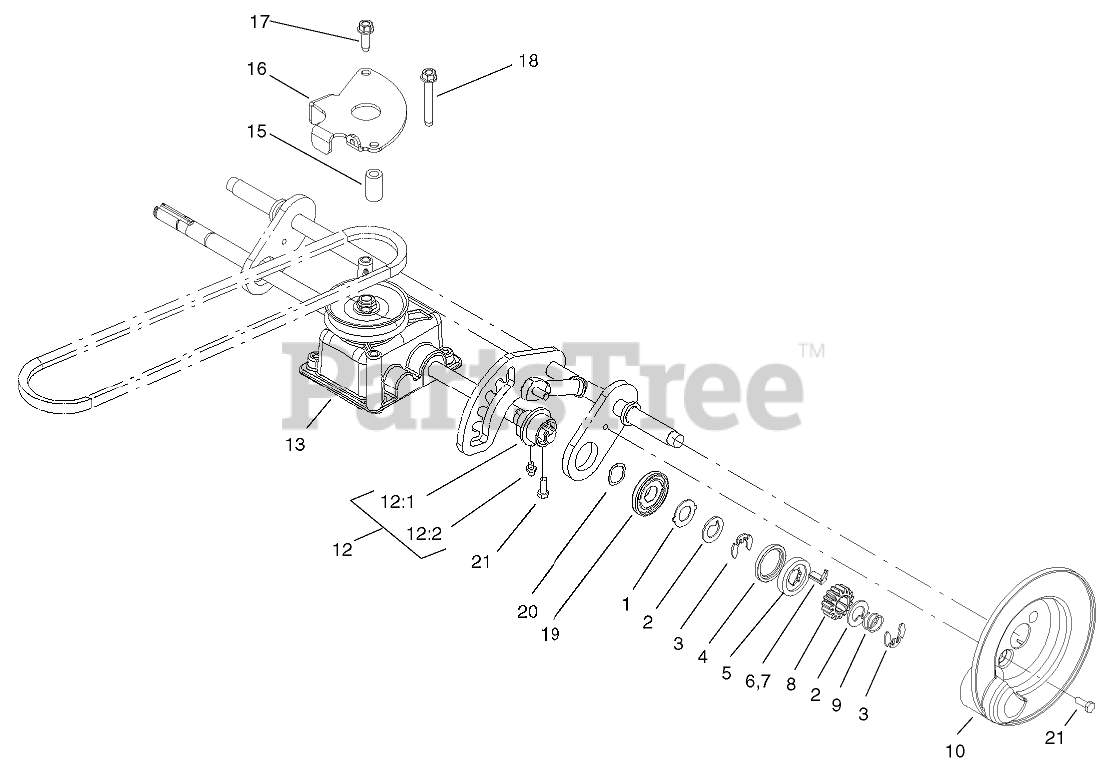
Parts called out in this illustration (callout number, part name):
1	WASHER-ARM, PIVOT
2	WASHER-THRUST, KEYED
3	RING-CLIP, LOCKING
4	RING-FRICTION
5	WASHER-CLUTCH
6	KEY-ROCKING, RH
7	KEY-ROCKING, LH
8	GEAR-PINION
9	SPRING-COMPRESSION
10	COVER-GEAR
12	BUSHING ASM
12:1	BUSHING
12:2	FITTING-GREASE
13	GEAR CASE ASM
15	BUSHING-PLATE, ACTUATOR
16	GUIDE-TRANSMISSION
17	SCREW-HWHTF
18	SCREW-HWHTF
19	RETAINER-RING
20	WASHER-WAVE
21	SCREW-TAPTITE
